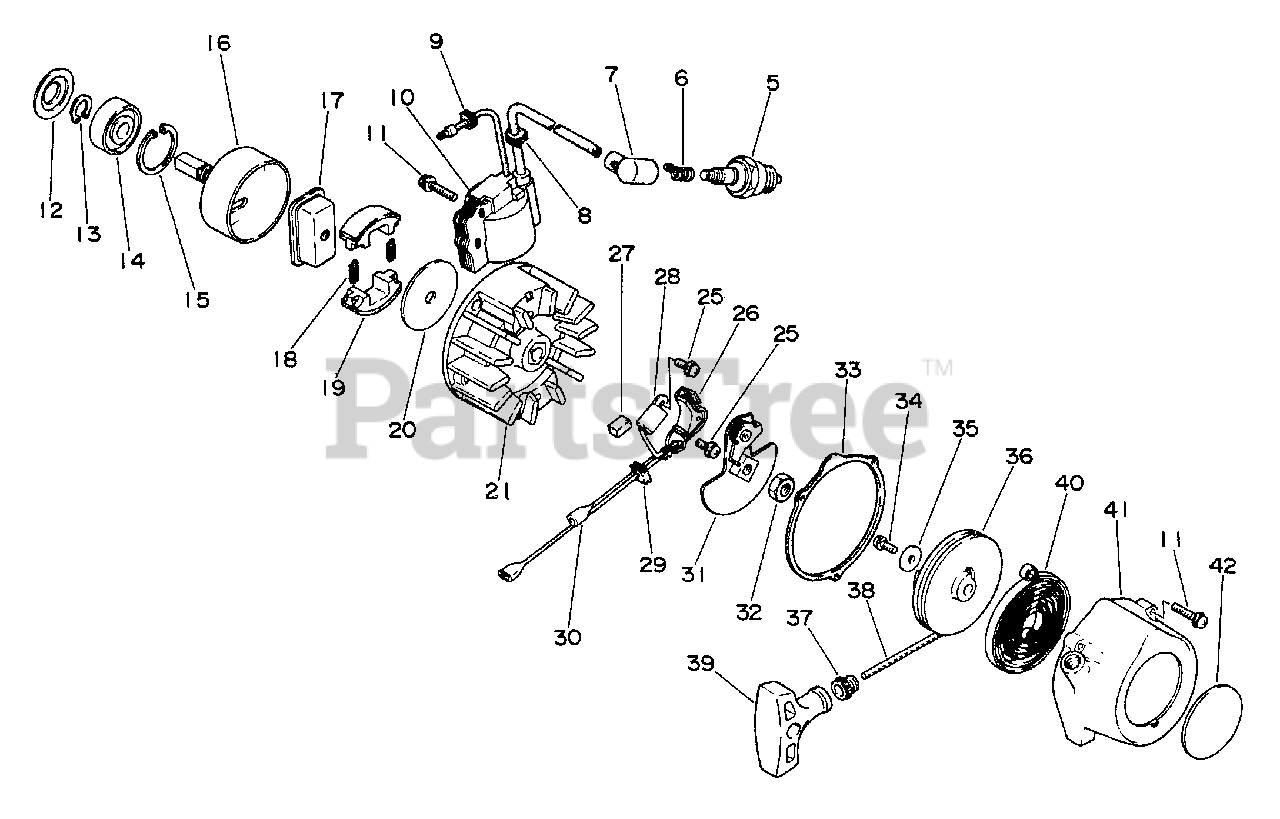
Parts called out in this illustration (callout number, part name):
5	SPARK PLUG - CJ8
6	TERMINAL, SPARK PLUG
7	CAP, SPARK PLUG
10	COIL, IGNITION
11	SCREW 4×20
12	STOPPER, PIPE
13	RING, RETAINING - 12
14	BEARING, BALL
15	RING, SNAP Ø32
16	DRUM, CLUTCH
17	BOSS, CLUTCH
18	SPRING, CLUTCH
19	SHOE, CLUTCH
20	PLATE, CLUTCH
21	FLYWHEEL
25	SCREW 4×10
26	CONTACT POINT SET
27	PAD, OIL
28	CONDENSER
29	GROMMET, LEAD
30	LEAD - GROUND
31	PAWL ASSY, STARTER
32	NUT 8×1.25
33	GASKET, STARTER
34	SCREW - 4×10
35	WASHER 4.1×15.5×1T
36	REEL, ROPE
37	ROPE, STARTER 3.0×850
38	GUIDE, ROPE
39	GRIP, STARTER
40	SPRING, RECOIL
41	CASE, STARTER
42	LABEL - ECHO
